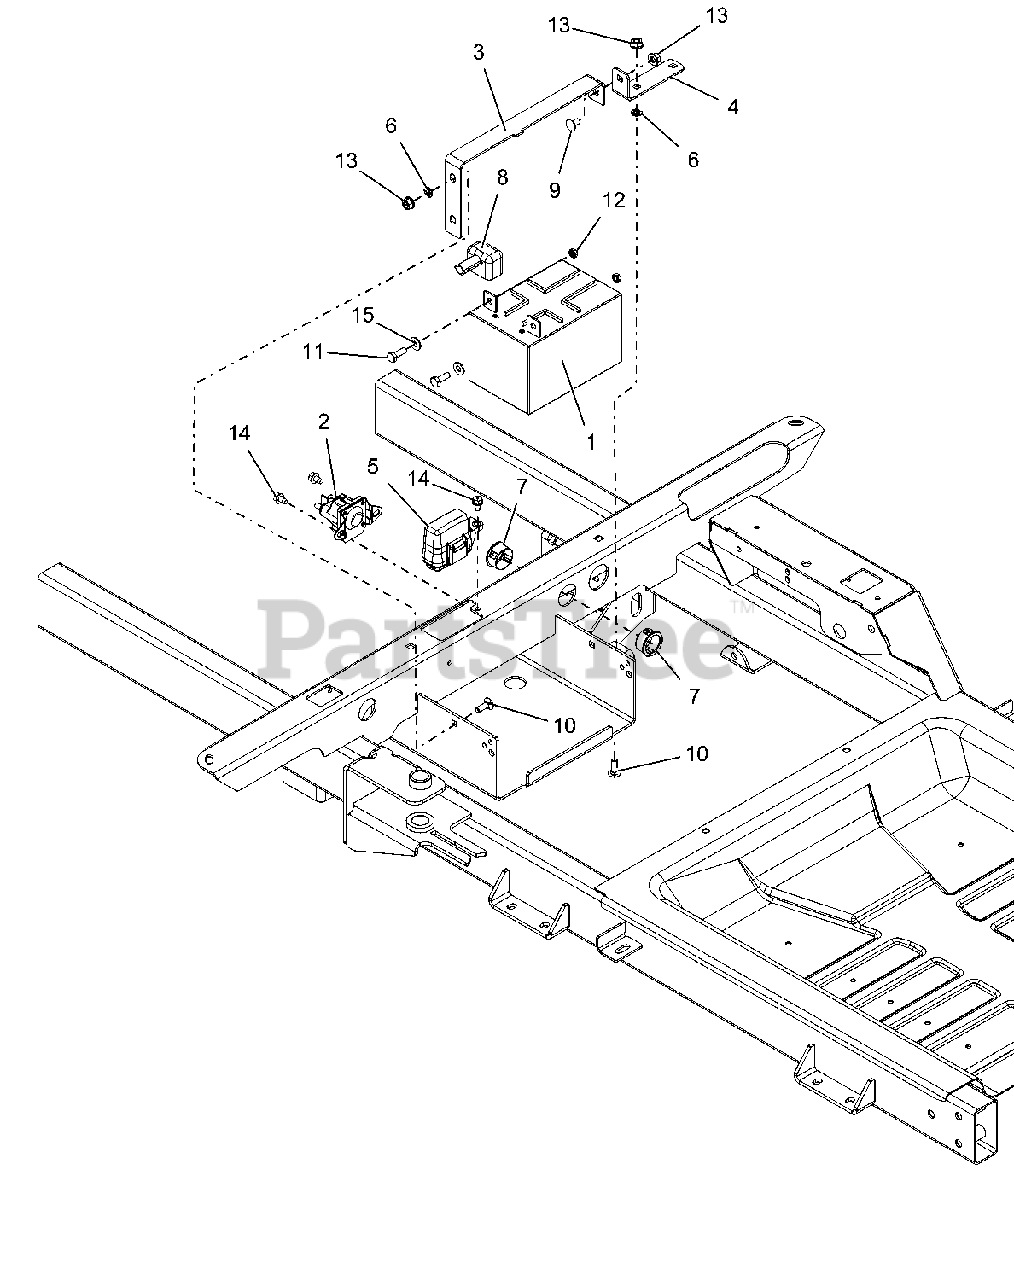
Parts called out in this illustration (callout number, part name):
1	BATTERY, 12V 12A -190CCA
2	SOLENOID, STARTER (SEALED)
3	BRKT, BATTERY HOLD-DOWN
4	BRKT, BATTERY (BLACK)
5	HARNESS, WIRE -2016 IKON/ZT-4POS
6	NUT, PUSH .25X.50 O.D.
7	BSHG, PANEL SNAP .937X1.109X.56
8	INSULATOR
9	BLT-RDHDSQNK .25-20X.50 G5 Y
10	BLT-RDHDSQNK .25-20X.75 G5 YWZC
11	BLT-HEX .25-20X.75 GR5 YWZC
12	NUT-KEPS 10-24
13	NUT, LK-TOP-FLG .25-20 YWZC
14	SCR-TAP .25-20X.37 HWH YWZ TR
15	WSHR-FL-STL.281X.62X.065 YWZC
